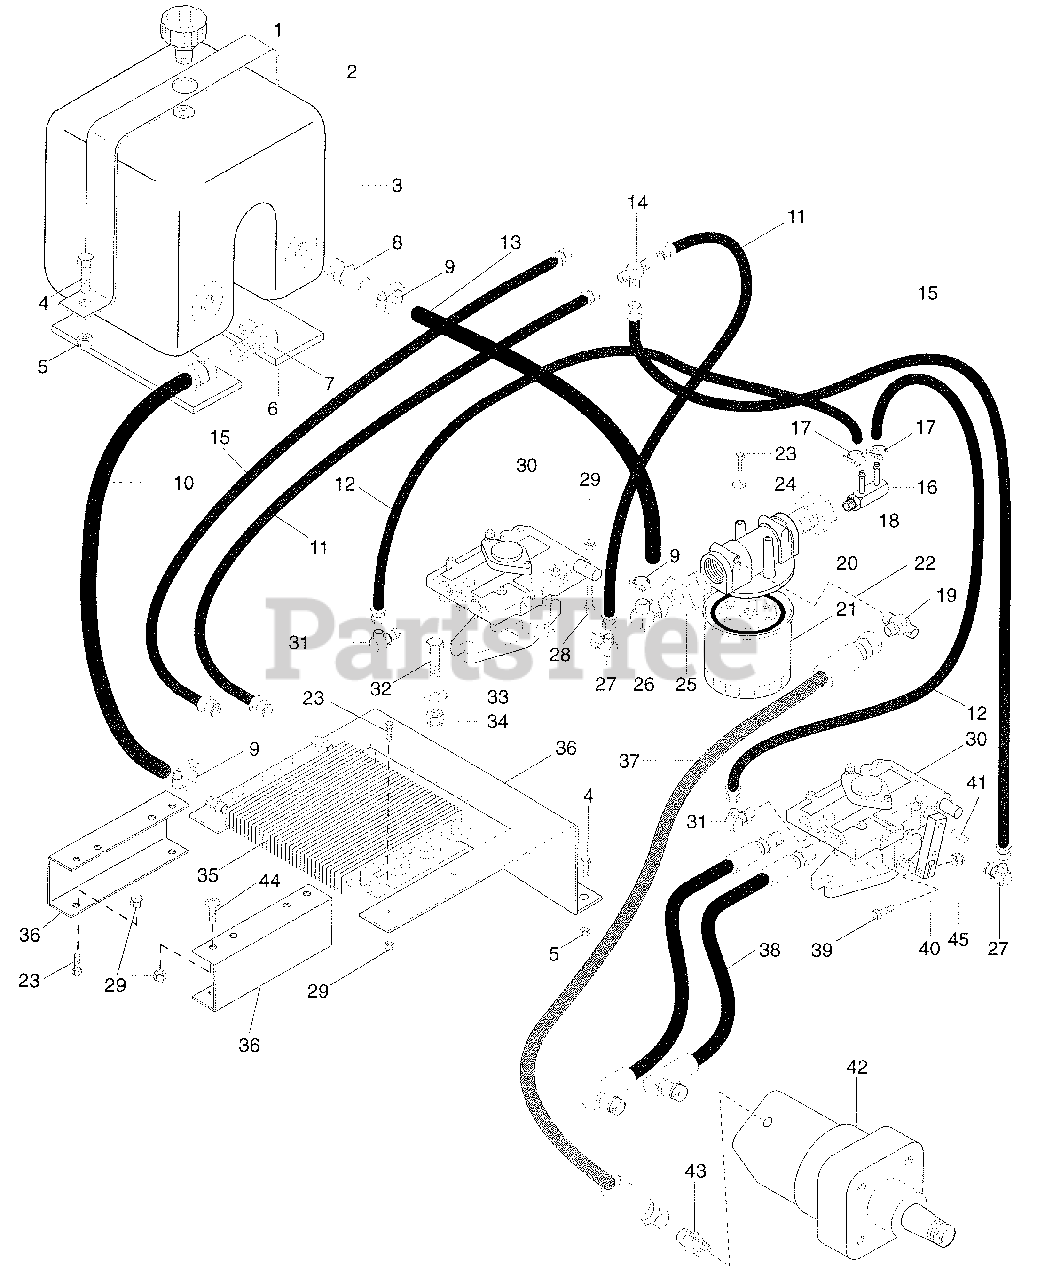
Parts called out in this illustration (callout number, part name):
1	Cap, Filter
2	Strap, Tank
3	Tank, Hydraulic
4	Boldt Hex .31-18 X .75 Grade 5
5	Nut Locking Nylon .312-18 Grade 2
6	Pad, Gas Tank
7	Adapter .37-.875
8	Fitting Adapter 88-14
9	Clamp, .88 Diameter Hose
10	Hose, Hydraulic Cooler to Tank (007, 008, 009, 012, 302)
11	Hose, Hydraulic Valve to Tank (007, 008, 009, 012, 302)
12	Hose, Oil Filter to Pump
13	Hose, .50 Inside Diameter X .75 OD
14	Adapter Tee .56-18
15	Hose, Pump to Tee (007, 008, 009, 012, 302)
16	Fitting Pipe .563-18
17	Clamp Hose 1.50 X .81 X 1.42
18	Adapter, Hydraulic 6410-12-06
19	Adapter, Hydraulic 2601-04-04-04
20	Head, Oil Filter
21	Replacement Element 921999
22	Assembly, Filter
23	Bolt Hexs .25-20 X .63
24	Washer Lock .250 Regular
25	Adapter Hydraulic .88-14
27	Adapter 2503-6-6
28	Bolt Hex .25-20 X 2.00 Grade 5
29	Nut Locking Nylon .250-20 Grade 2
30	Variable Displace Pump
31	Adapter 2503-6-4
32	Bolt Hex .38-16 X 1.125
33	Washer Flat Steel .406 X .812 X .065
34	Nut Locking Center .625-10 Grade 2
35	Cooler, Oil
36	Bracket, Oil Cooler (007, 008, 009, 012, 302)
37	Hose Assembly, Motor to Oil Filter
38	Assembly, Hose Wheel Motor to Pump
39	Bolt Hex .25-20 X 1.25 Grade 5
40	Arm, Pump Actuating
41	Pin Dowel .312 X 1.25
42	Motor, Wheel
43	Adapter 0503-4-4
44	Screw Machine .25-20
45	Nut Locking Flange .250-20
